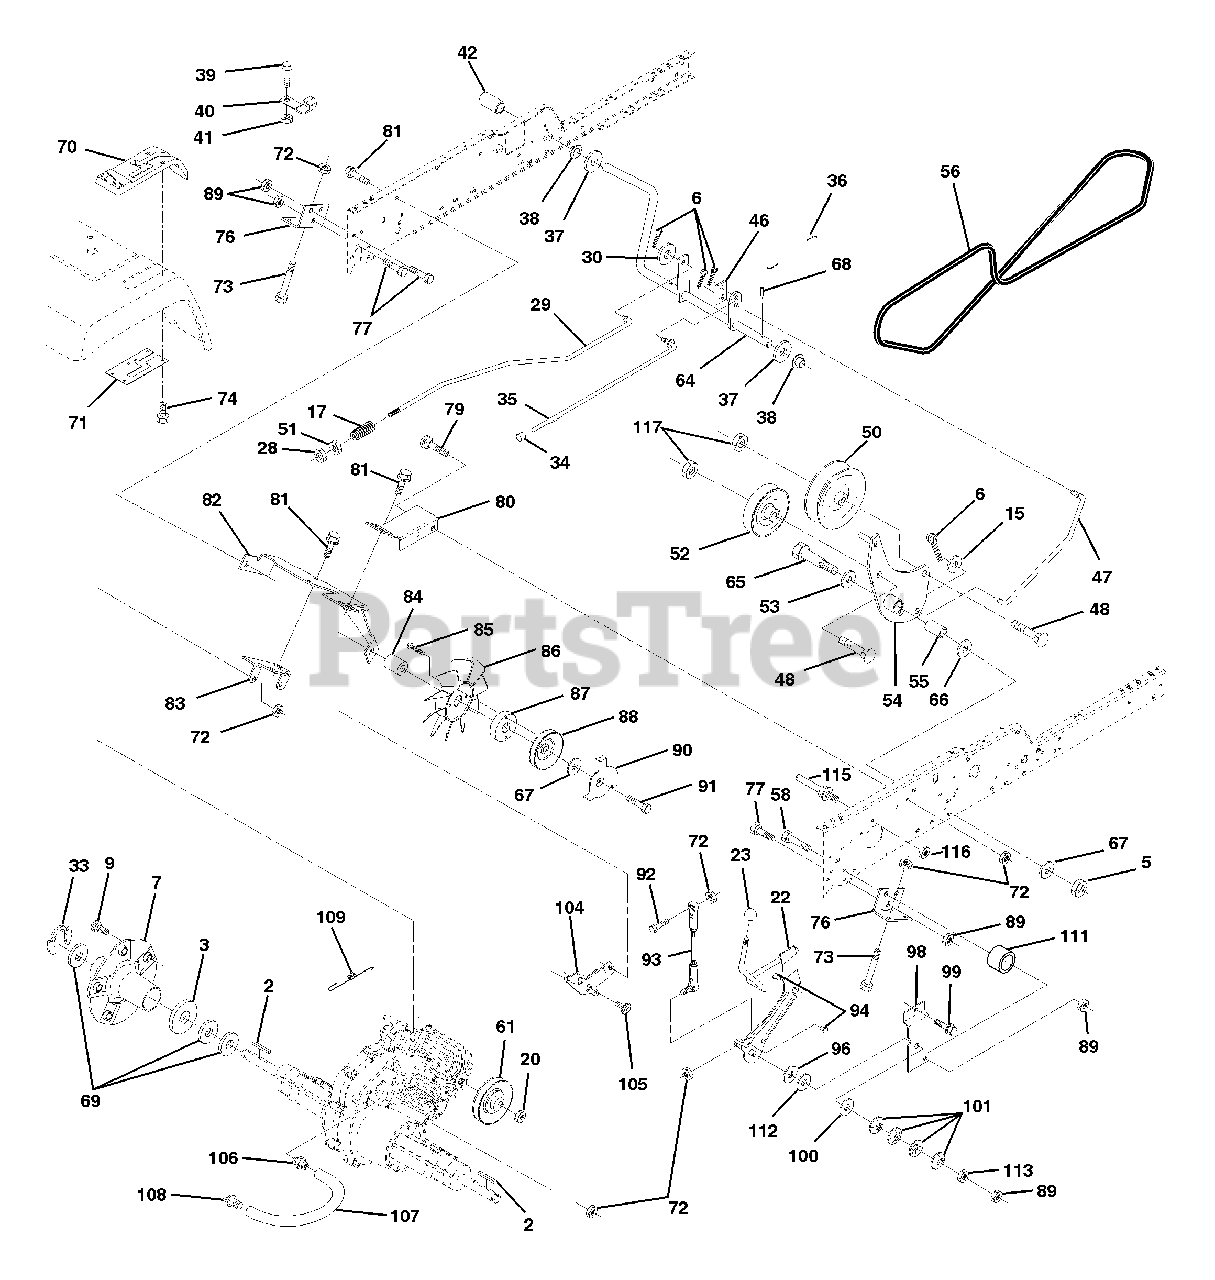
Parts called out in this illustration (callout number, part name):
2	Key 1/4 x 2.5
3	Washer Thrust Axle Harden
5	Nut Crownlock 3/8-16
6	Pin Cotter 1/8 x 3/4
7	Wheel Hub Asm.
15	Washer 13/32 x 13/16 x 16 Ga.
17	Spring Rod Brake
20	Nut Hex Jam Toplock 1/2-20
22	Shaft Arm Asm
28	Nut, Hex Jam 3/8-16
30	Washer 13/32 x 1 x 16 Ga.
34	Cap Plunger
35	Rod Parking Brake
36	Spring Drive Ground
37	Washer 25/32 x 1-1/4 x 16 Ga.
39	Screw Fin #10-24 x 1
40	Actuator Interlock Switch
41	Nut Toplock #10-24 UNC
42	Cover Pedal
46	Retainer Spring
47	Clutch Rod
48	Bolt Carriage 3/8-16 x 1-1/2 Gr. 5
50	Pulley Idler Flat
51	Nut Lock Hex 3/8-16
52	Pulley Idler Grooved
53	Washer Hartdened
54	Clutch Arm Asm
55	Bearing, Idler
58	Bolt Fin Hex 7/16-14 x 1-1/2
61	Pulley Transaxle
64	Shaft Asm Brake Parking Clutch
65	Bolt Shoulder
66	Washer Hardened
67	Washer 13/32 x 13/16 x 12 Ga
70	Console Hydro Fender
71	Plate Console Shift
72	Locknut Hex W/Washer Insert
73	Bolt Fin Hex 5/16-18 x 3
74	Screw, Hex Wsh Hi-Lo 1/4-1/2
76	Bracket Transaxle
77	Bolt Fin Hex 7/16-14 x 1
78	Washer 11/32 x 3/4 x 12 Ga.
79	Bolt Carriage 5/16-18 x 5/8
80	Bracket Torque RH
81	Screw Thdrol 3/8-16 x 3/4
82	Bracket Mount Torque/Fan
83	Strap Torque Mid
85	Screw #10-24 x 1-1/4
86	Fan 7" Hydro
87	Adapter Fan
88	Pulley Idler
89	Nut, Crownlock 7/16-14
90	Keeper Belt
91	Screw Thdrol 3/8-16 x 2-3/4
92	Bolt Fin Hex 5/16-18 x 1.75
93	Link Shift Asm
94	Fastner Christmas Tree
96	Washer Nickel Plated
98	Bracket Shift
99	Screw Thdrol 3/8-16 x 1-1/2
100	Washer Compression
101	Washer Bellville
104	Bracket Idler
105	Screw Tap 1/4-20 x 1/2
106	O-Ring Asm. Hydro Gear
107	Line Fuel Hydro
108	Cap Vent
109	Spring Return Brake
111	Spacer Shift Lever VGTH
112	Washer Nylon High Temp
113	Nut Hex ASF 7/16-14 UNC
115	Keeper Belt Gnd Dr.
116	Nut Lock Hex Flange 5/16-18
117	Nut Lock Flg. 3/8-16 UNC
